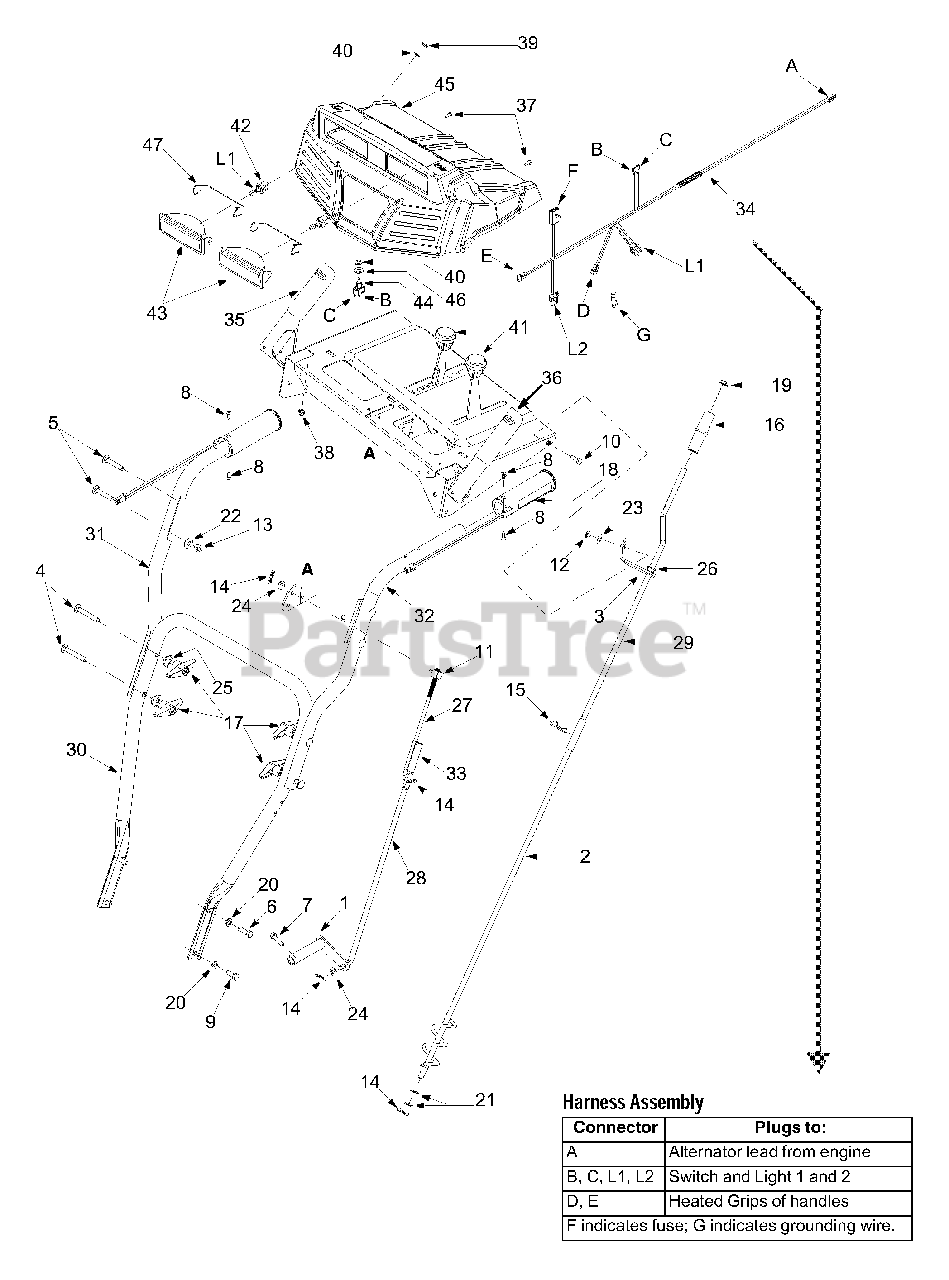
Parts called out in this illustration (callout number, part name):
4	Carriage Screw 5/16-18 x 2.25"
5	Carriage Bolt 5/16-18 x 1.75"
6	Hex Screw 5/16-18 x 1.0"
7	TT Screw 1/4-20 x 1.0"
9	Hex Screw 5/16-18 x 0.75"
10	Hex Screw 1/4-20 x 0.75"
11	Ferrule
12	Hex Nut 1/4-20
13	Lock Nut 5/16-18
14	Hairpin Clip
15	Click Pin
16	Chute Crank Knob
18	Heated Grip
20	Lock Washer
21	Flat Washer
22	Bell Washer
23	Bell Washer
24	Flat Washer
25	Saddle Washer
26	Plastic Bushing
27	Shift Rod: Upper
28	Shift Rod: Lower
34	Harness Assy.
35	Handle Engagement RH: Black
36	Handle Engagement LH: Black
37	B Screw #10-16 x 0.625"
40	Toggle Switch
41	Shift Knob
42	Halogen Lamp
43	Lamp Housing
44	Toggle Switch
45	Handle Panel
46	Flat Washer .474 x .879 x .064
47	Headlight Retainer
